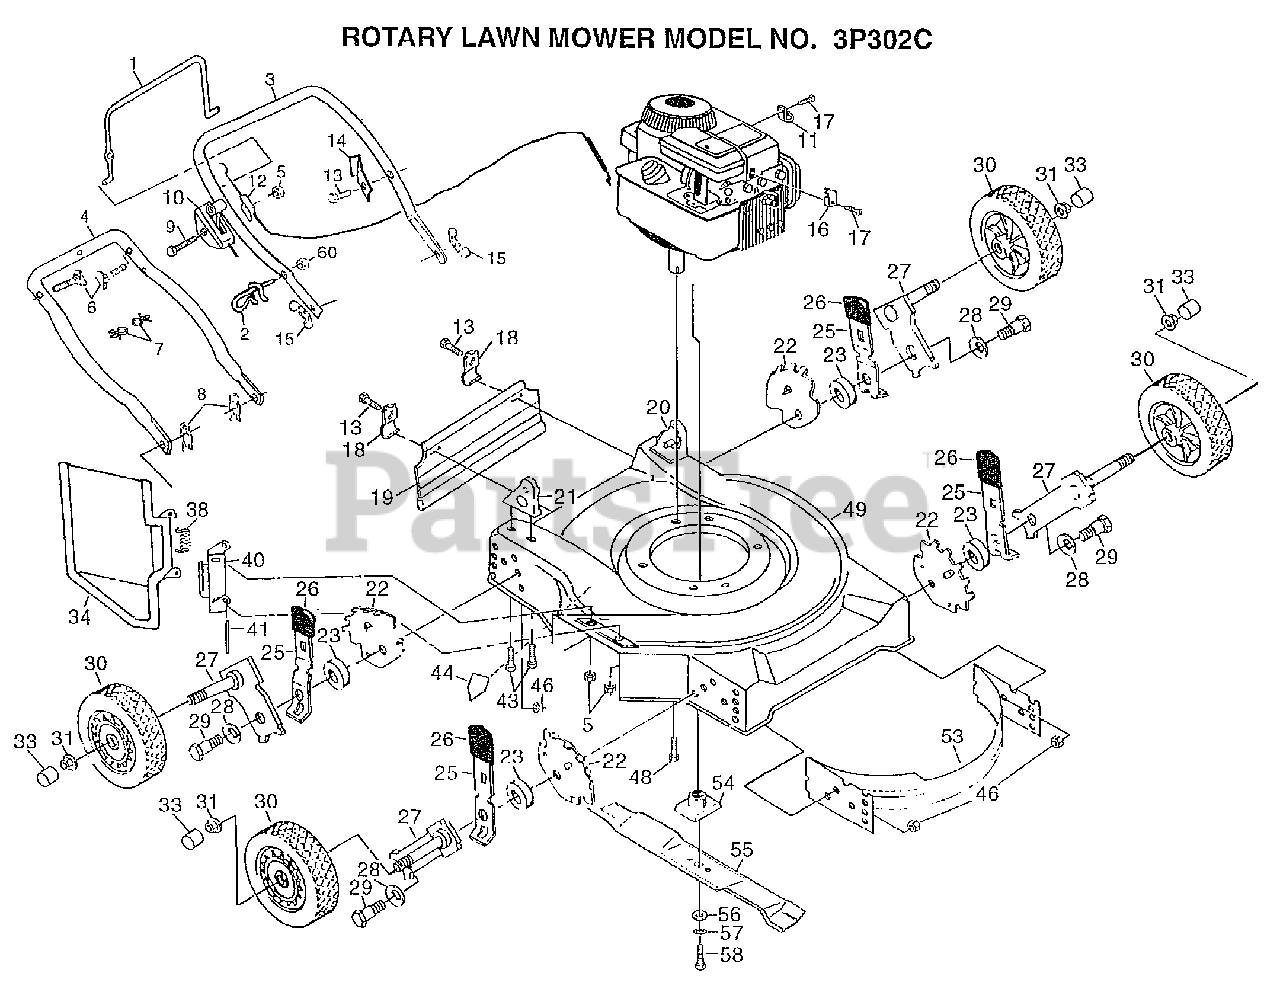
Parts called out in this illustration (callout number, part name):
1	CONTROL BAR
2	ROPE GUIDE
4	LOWER HANDLE
6	BOLT.HANDLE.LM
8	HAIRPIN COTTER
9	SCREW.HXHD.WASH.
10	CONTROL THROTTLE
11	GUIDE CLIP PM
12	"CABLE,ENG ZONE CO"
13	TAPPING SCREW
14	"BRKT,UPSTOP"
15	"NUT,WING PM"
16	CABLE CLAMP
17	SCREW PM
18	"BRKT,DEFL PM"
19	SKIRT.REAR.22SD.
20	HDLE BRKT ASSY LH
21	HDLE BRKT ASSY.RH
22	BRACKET.ADJ.9POS.
23	SPACER.HEIGHT.ADJ
25	SPRING SELECTOR
26	KNOB PM
27	ARM.AXLE.ASM.BZP.
28	"WASHER, BELLEVIL."
29	BOLT SHLD 3/8-16
30	WHEEL.ASM
31	HEX FLANGE LOCKNT
33	HUB CAP-PLASTIC
34	GUARD.DISCH.22SD.
40	BRACKET.HINGE.W/F
41	ROD.HINGE.COMBI-C
43	SCREW 5/16-18X3/4
44	DECAL HYT
46	LOCKNUT PM
48	BOLT.ENG.3/8-16
49	KIT HOUSING MOWER
53	BAFFLE.FRT/REAR
54	BLADE ADAPTOR
55	"BLADE.MULCH.22"""
56	"WASHER,HARDEN"
57	LOCKWASHER
58	SCREW
60	NUT
